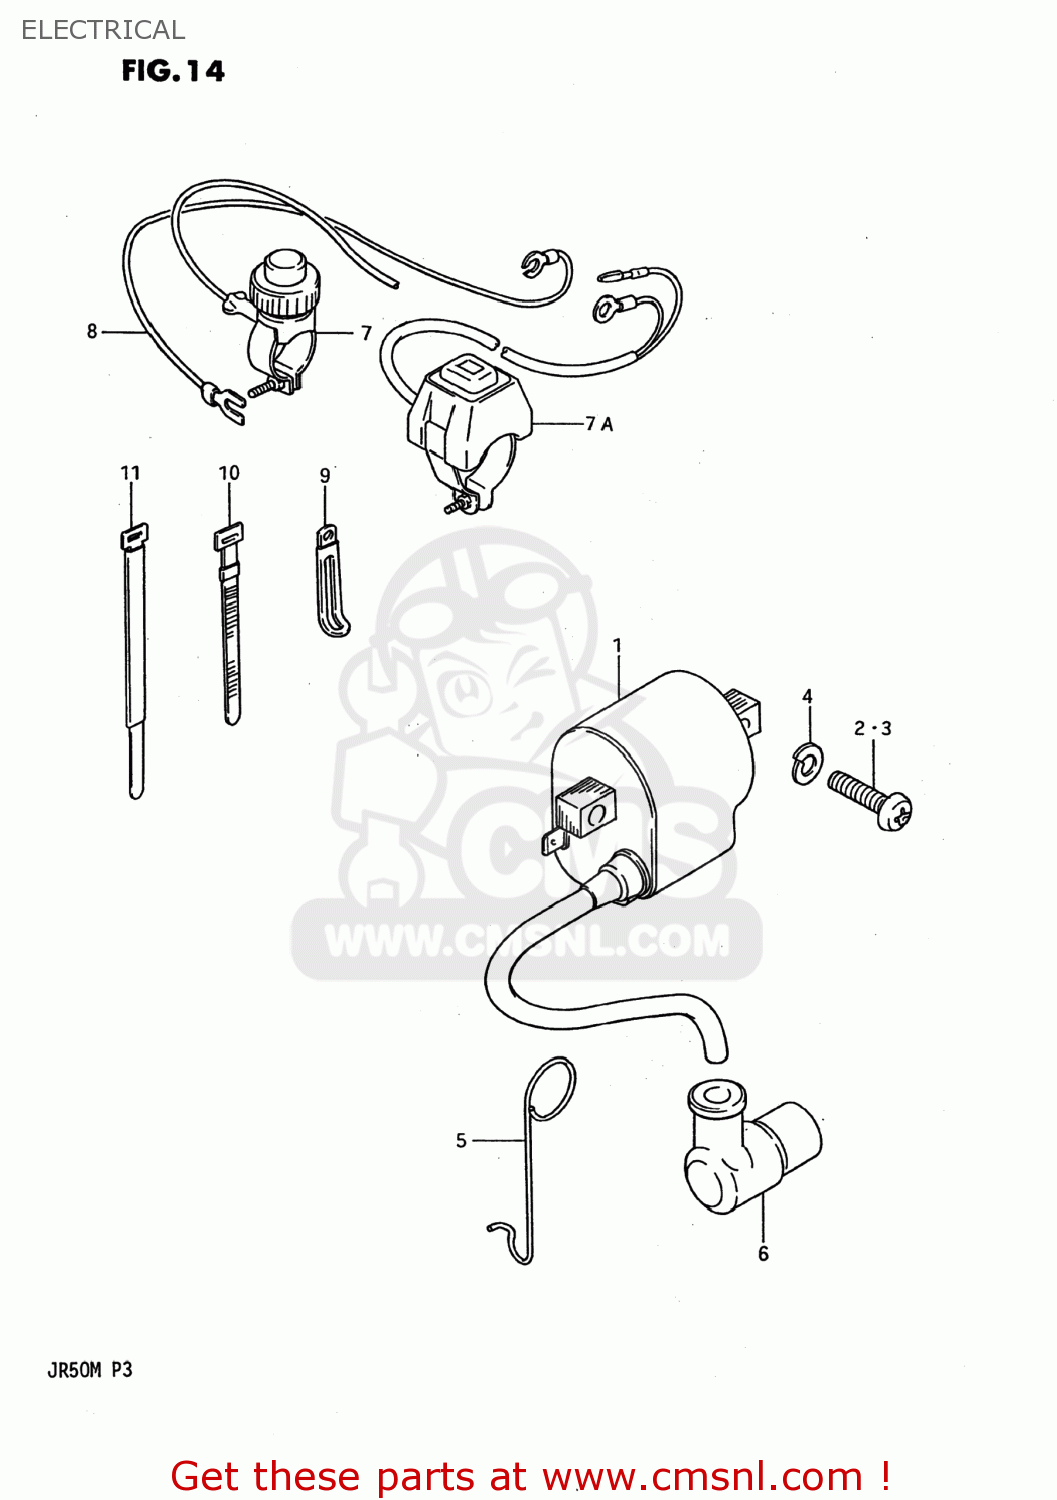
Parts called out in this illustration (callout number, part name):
1	COIL ASSEMBLY,IGNITION
2	SCREW
3	SCREW
4	WASHER,LOCK
5	CLIP
6	CAP,SPARK PLUG
7	SWITCH ASSEMBLY
7A	SWITCH ASSEMBLY
8	WIRE
9	CLAMP
10	CLAMP(L:120)
11	CLAMP
